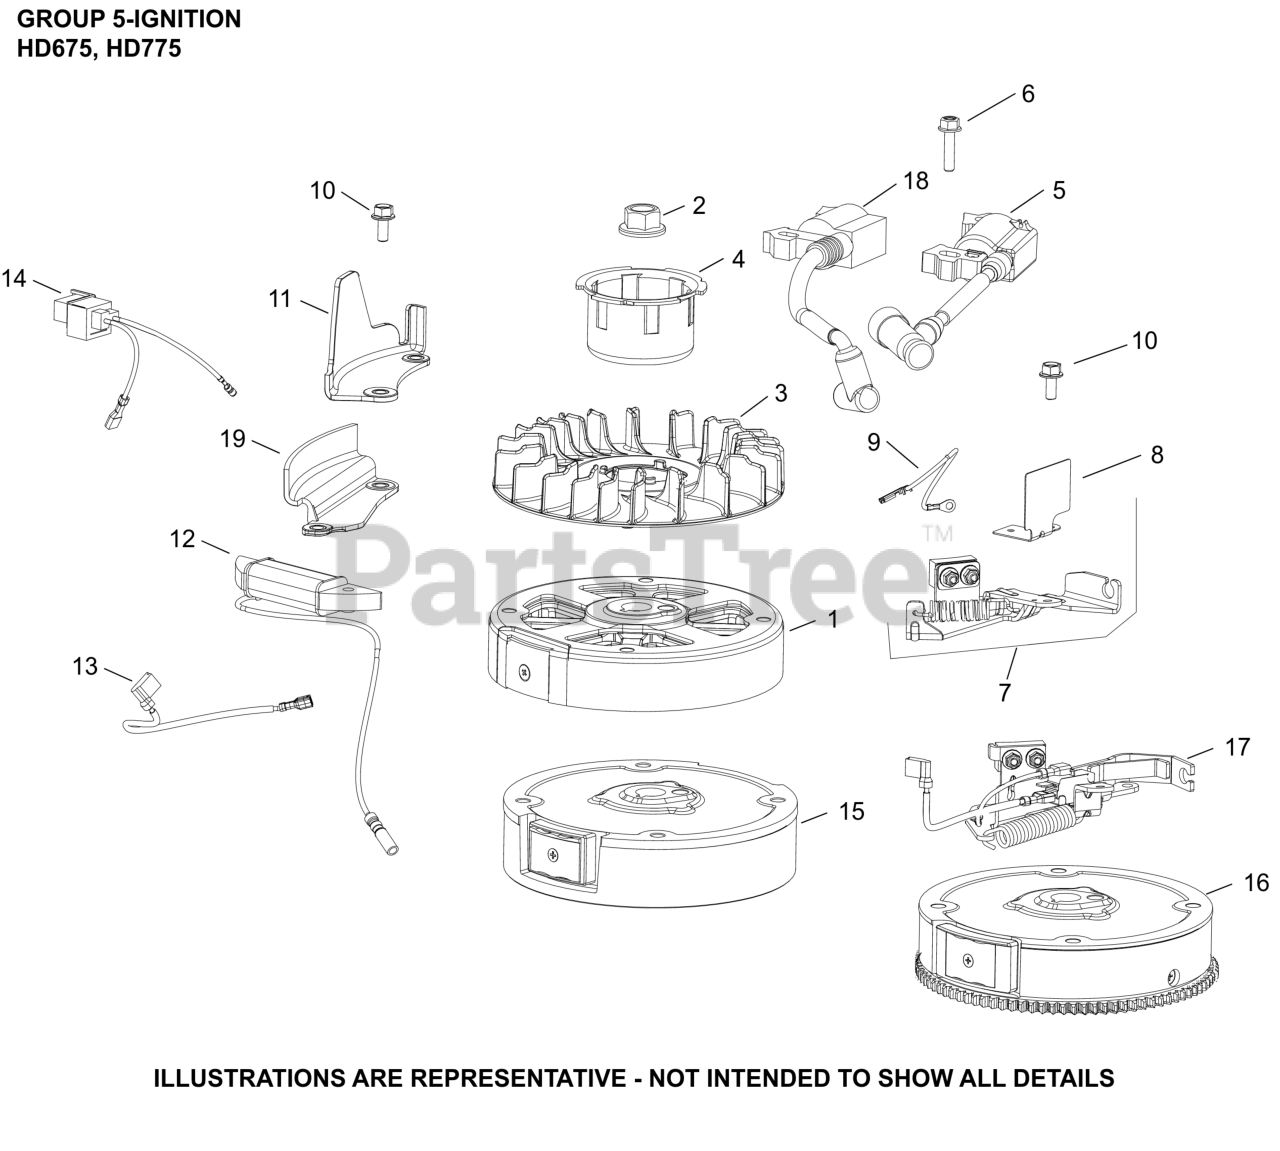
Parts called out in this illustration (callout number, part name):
2	NUT, FLYWHEEL (W/SERRATIONS)
3	FAN, FLYWHEEL
4	CUP, STARTER DRIVE
5	MODULE IGN (#1458416S)
6	SCREW, M6 X 25-(#25086436S)
11	GUARD, FINGER
15	FLYWHEEL (CAST IRON)
